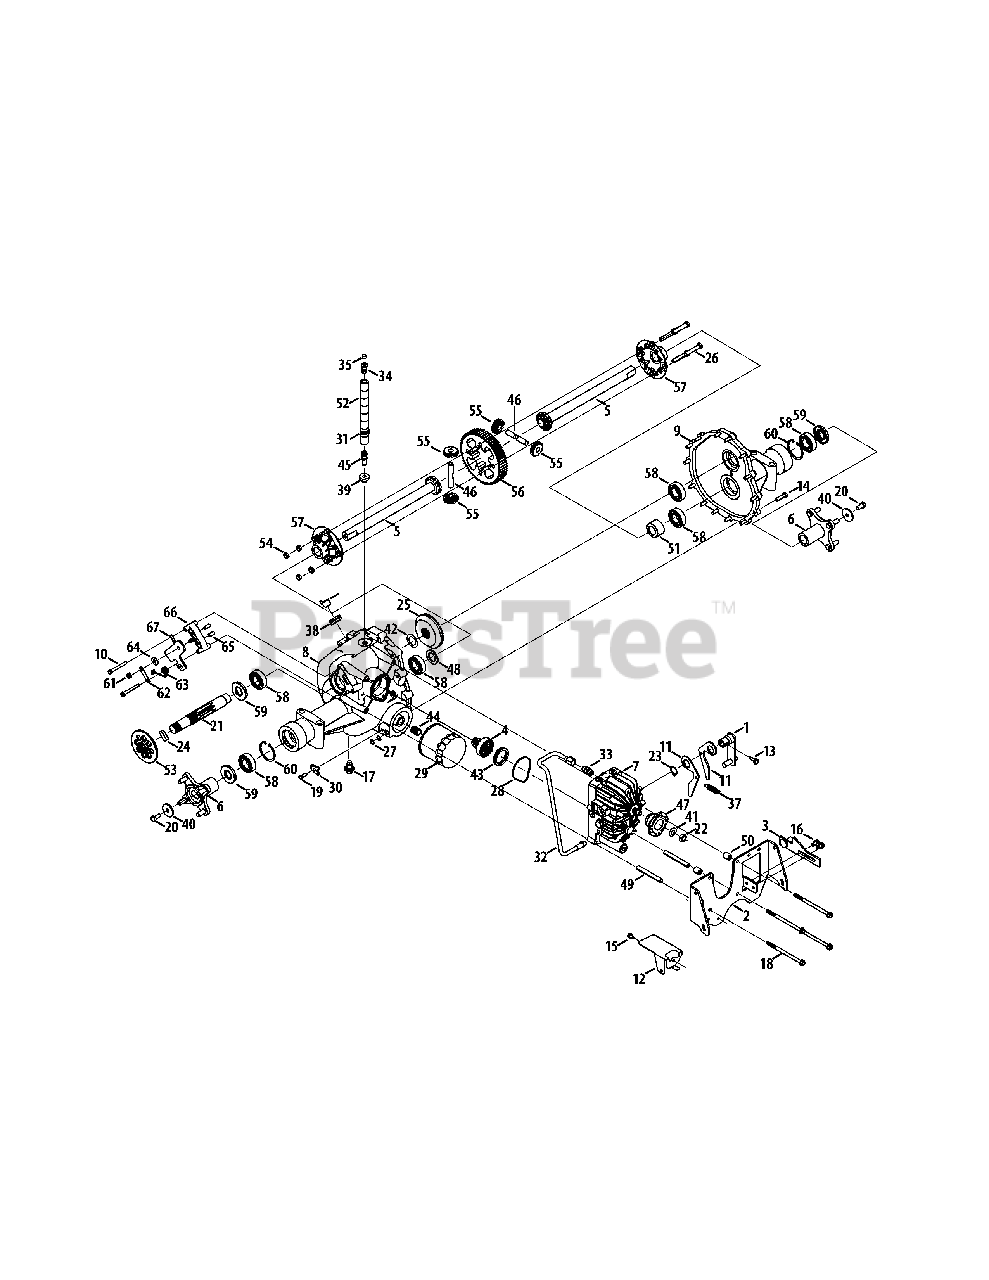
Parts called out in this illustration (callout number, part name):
1	Neutral Return Arm Assembly
2	Torq Bracket Assembly
3	Neutral Return Arm Assembly
4	Pinion Gear, 13T
5	Axle Shaft DD
6	Wheel Hub Assembly
7	Pump Assembly, Hydrostatic
8	RH Housing
9	LH Housing
10	Hex Washer Screw, 1/4-20 x 2.375
11	Neutral Arm
13	Hex Screw, 5/16-24 x .625
14	Hex Lock Screw, 5/16-18 x 1.25
15	Hex Washer Screw, 1/4-20 x .500
16	Hex Washer Screw, 5/16-18 x .500
17	Plug Screw, M14 x 1.5 x .827
18	Hex Washer Screw, 5/16-18 x 5.350
19	Hex Screw, 1/4-20 x .75
20	Hex Lock Screw, 3/8-16 x .750
21	Output Shaft, 9T
22	Jam Lock Nut, 1/2-20
23	Retaining Ring, .875
24	Brake Pad
25	Bevel Gear, 54T
26	Hex Screw, 3/8-16 x 2.00
27	0-Ring, .426 x .566 x .070
28	Gland Seal
29	Oil Filter
30	Tube Clamp, .500
31	Fuel Clamp
32	Hydro Pick-Up Tube
33	Straight Fitting
34	Plastic Vent
35	Plastic Vent Cap
37	Extension Spring, .50 x 1.98
38	Rubber Grommet, .750 x 1.063 x .4375
39	Grommet, .362 x .56 x .63
40	Flat Washer, .390 x 1.500 x .134
41	Bell Washer, .525 x 1.00 x .050
42	Thrust Washer, 1.007 x 1.542 x .03
43	Spring Washer, 1.595 x 2.011 x .030
44	Filter Nipple Fitting
45	Tube Fitting, .500
46	Shaft, .500 x 3.005
47	Hydro Pump Adapter
48	Axle Spacer, 1.007 x 1.665 x .141
49	Hydro Spacer, .323 x .443 x 3.51
50	Hydro Spacer, .323 x .600 x .740
51	Axle Spacer, 1.007 x 1.665 x .989
52	Fuel Line, 1/2
53	Disc Brake
54	Jam Lock Nut, 3/8-16
55	Miter Gear
56	Spur Gear
57	RH Housing Differential
58	Ball Bearing, 1 x 52 x 15
59	Oil Seal, 1.00 x 2.047 x .2755
60	Retainer Ring
61	Hex Lock Nut, 5/16-24
62	Anti-Rotation Brake Bracket
63	Torsion Spring, .75 x 3
64	Flat Washer, .343 x .880 x .062
65	Brake Actuator Pin
66	Brake Yoke
67	Brake Arm Actuator
